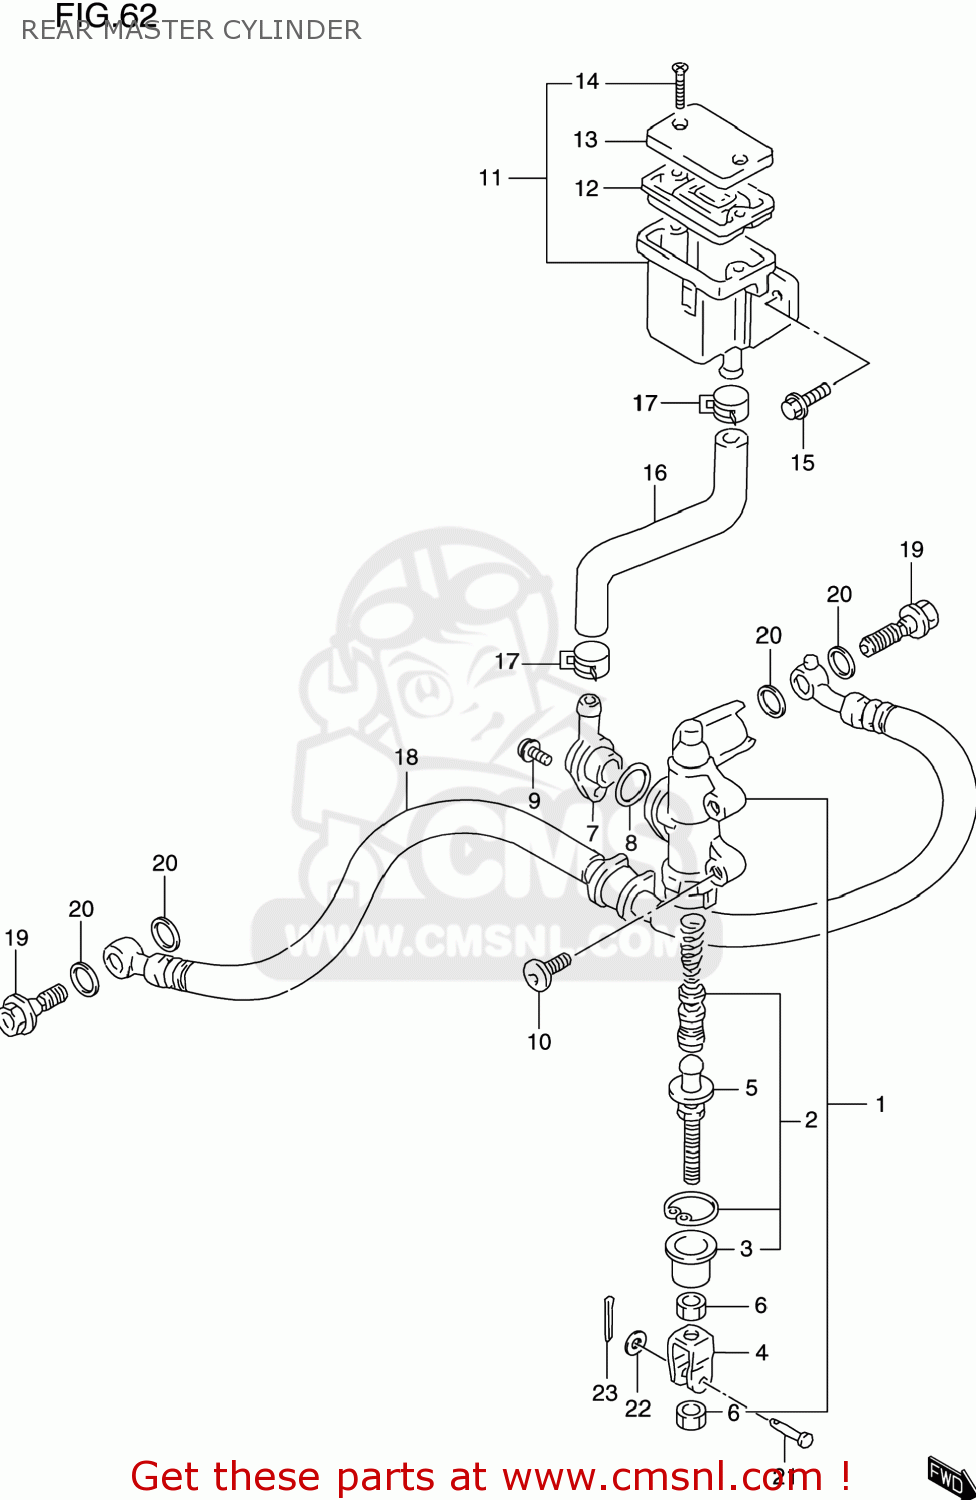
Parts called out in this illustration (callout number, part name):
1	CYLINDER ASSY,RR MASTER
2	PISTON/CUP SET
3	BOOT
4	YOKE
5	ROD,PUSH
6	NUT
7	CONNECTOR
8	O RING
9	SCREW
10	SCREW(6X20)
11	TANK ASSY,RESERVOIR
12	DIAPHRAGM
13	CAP
14	SCREW
15	BOLT
16	HOSE,RESERVOIR TANK
17	CLIP
18	HOSE,RR BRAKE
19	BOLT UNION
20	WASHER(10X15X1.5)
21	PIN
22	WASHER
23	PIN
